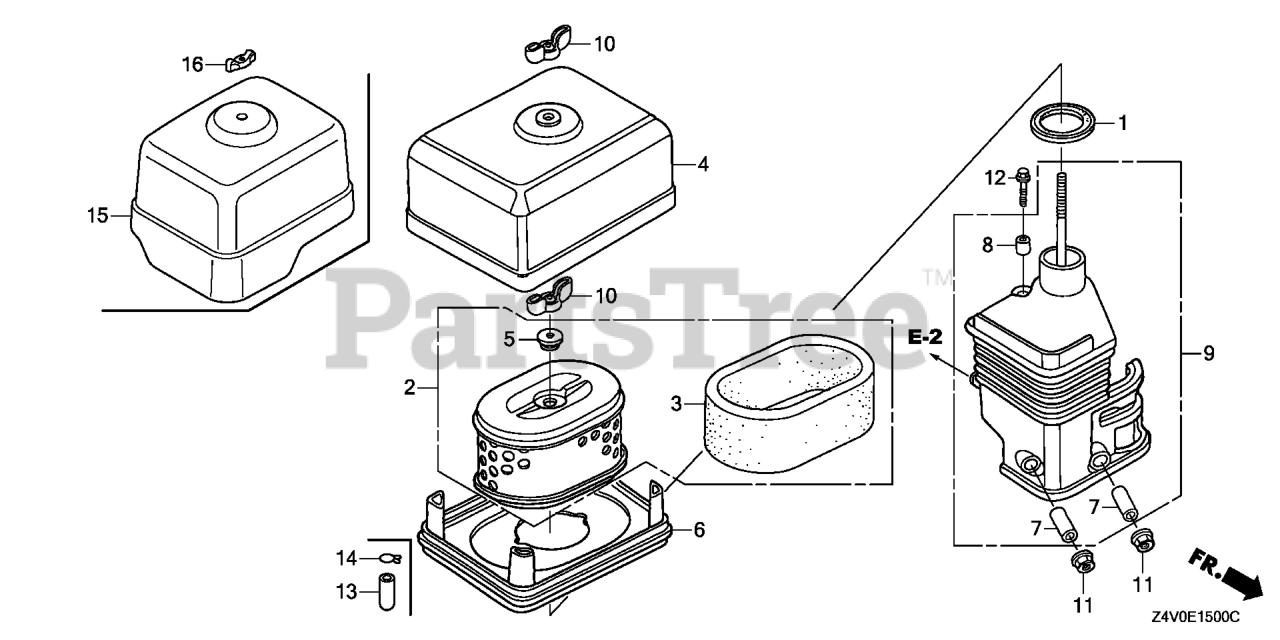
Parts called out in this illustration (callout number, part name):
1	GASKET, ELBOW
2	ELEMENT, AIR CLEANER (DUAL)
3	FILTER (OUTER)
5	GROMMET, AIR CLEANER
6	NOSE, MUFFLER
7	COLLAR, AIR CLEANER Use from Engine SN 1786085.
8	COLLAR B, AIR CLEANER
9	ELBOW, AIR CLEANER
10	WINGNUT, TOOL BOX SETTING
11	NUT, FLANGE (6MM)
12	BOLT, FLANGE (6X20)
15	COVER, AIR CLEANER
16	NUT, AIR CLEANER
